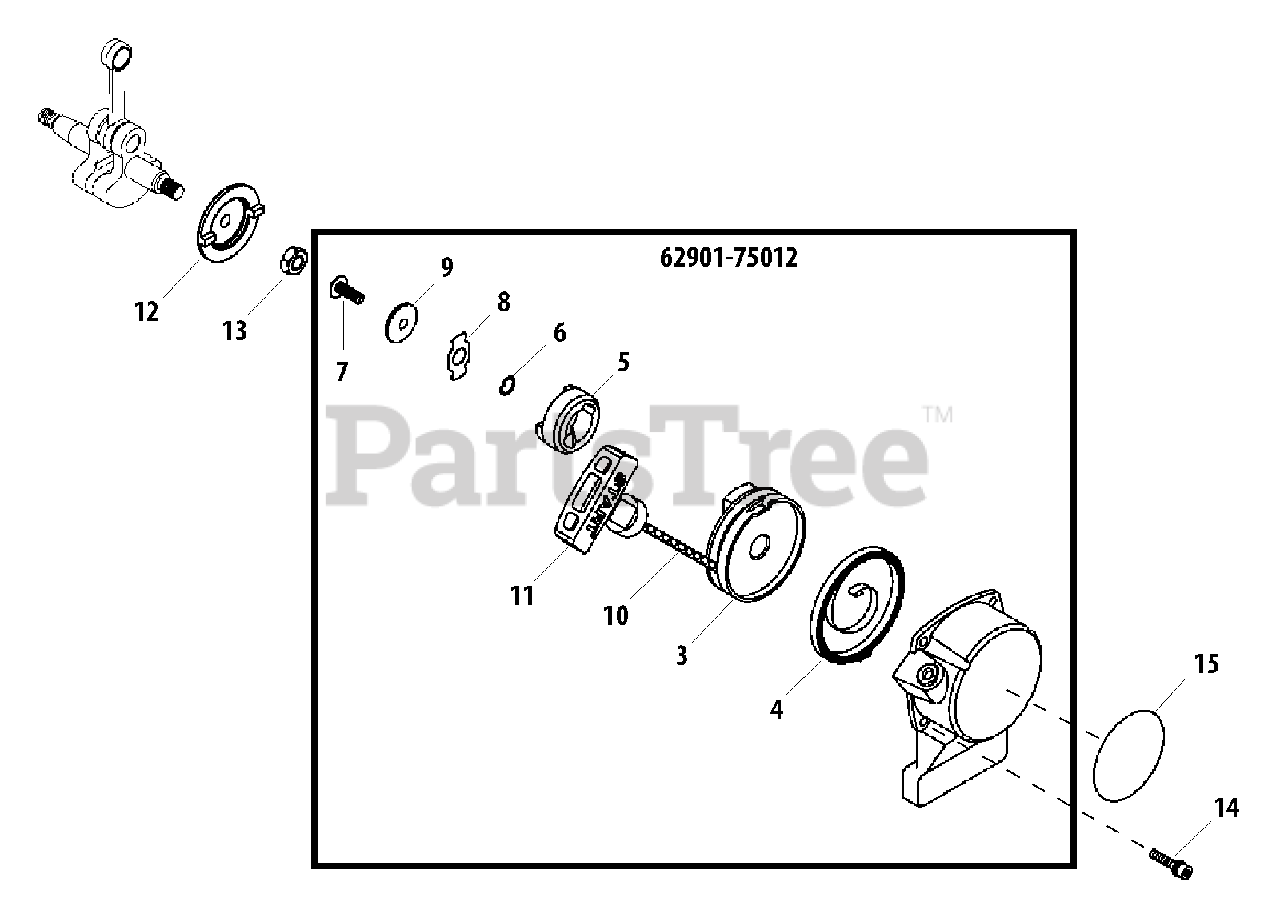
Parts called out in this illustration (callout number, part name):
3	REEL, ROPE
4	SPRING, RECOIL
5	PAWL, STARTER
6	WASHER, WAVE
7	SCREW 5 MM
8	RETAINER
9	WASHER 5 MM
10	ROPE, STARTER
11	GRIP, STARTER
12	PULLEY, STARTER
13	NUT M8×1
14	BOLT M4×16
15	LABEL, RECOIL C4
62901-75012	STARTER ASSY, RECOIL
